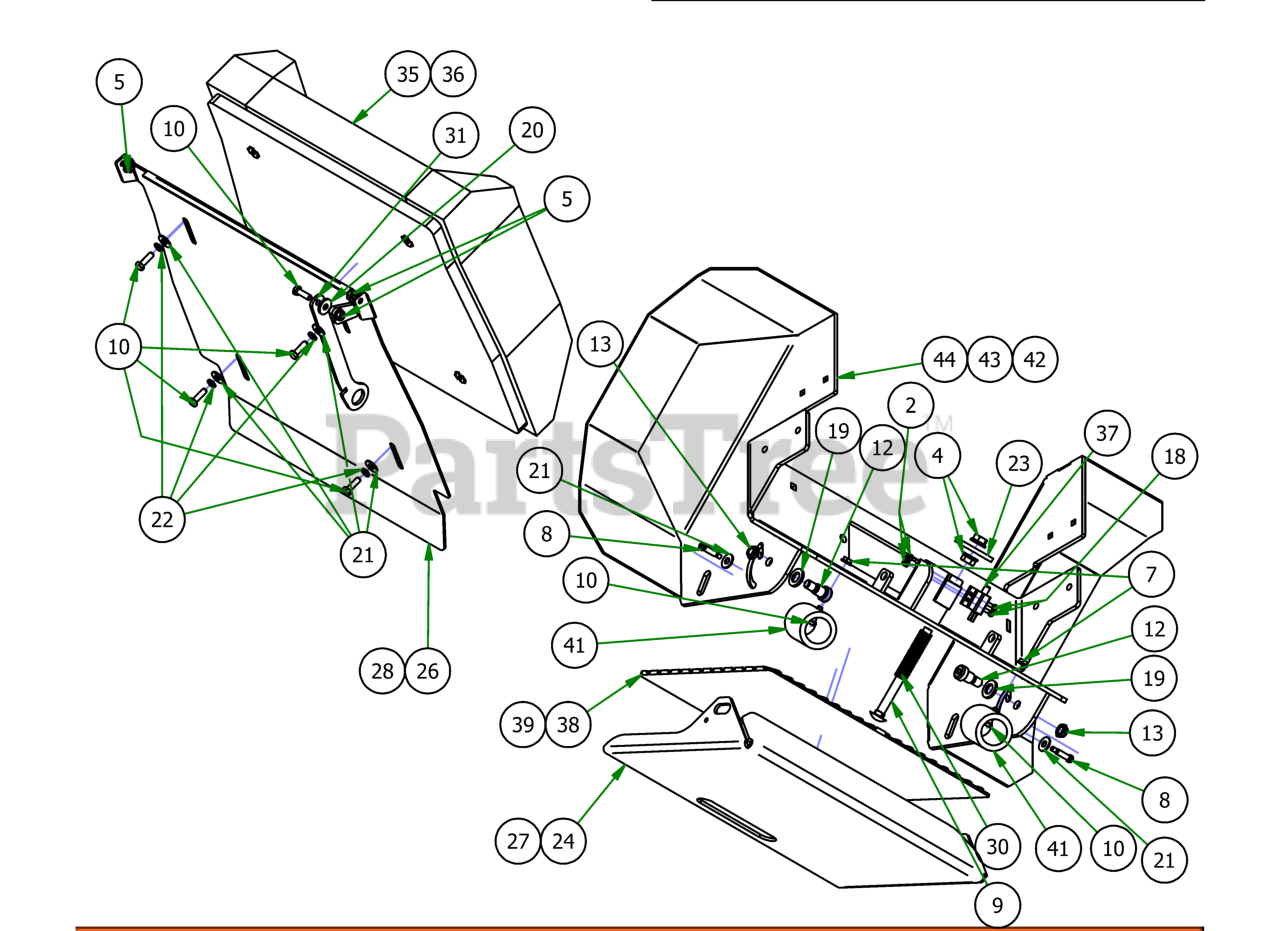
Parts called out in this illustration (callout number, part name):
1	3326 Wellnut (1/4-20 x 5/18")
2	10-24 Nylon Insert Locknut Zin
3	3/8 Nylock Flange Nut
4	1/2-13 HEX SERRATED FLANGE NUT HARD/ZINC
5	5/16-18 Nylon Flange Nut
6	1/4-20 Nylon Insert Locknut Zi
7	5/16-18 Hex Flange Nuts Zinc w
8	Steel Shoulder Screw 1/4"-20 x 7/8" Diameter 5/16"
9	1⁄2-13 x 6 Carriage Bolt, 2” min threads, Grade 2
10	5/16-18 X 1 GR 5 Hex Bolt Zinc
11	3/8-16 X 2 HEX CAP SCREW (GR.5) ZINC
12	5/8 X 5/8 SOCKET SHOULDER BOLT ZINC YELLOW
13	1/2-13 NYLON INSERT JAM LOCKNUT ZINC
14	5/16-18 X 1-1/4 CARRIAGE BOLT ZINC
15	3/8-16 X 1-1/4 HEX CAP SCREW (GR.5) ZINC
16	3/8-16 X 1-1/4 Carriage Bolt
17	1/4-20 X 3/4 GR 5 Hex Bolts
18	10-24 X 3/4 BUTTON SOCKET CAP SCREW 18-8 STAINLESS STEEL
19	.635 ID X 1.120 OD X .140 THICK FLAT WASHER NYLON
20	.360 ID X .983 OD X .120 THICK FLAT WASHER NYLON
21	5/16 USS FLAT WASHER (7/8 OD) ZINC
22	5/16 SPLIT LOCKWASHER ZINC
23	MZ Deck Idler Spacer
24	2019 Stand-On Platform
25	2019 Stand On Access Panel
26	2019 Stand On Pad Plate Weldment
27	2020 36" Stand-On Platform Plate-RAW
28	2020 36 Stand On Pad Plate Weldment
29	1/4"-20 x 3/4" Knurled Thumb Screw
30	Rider Presence Spring 9657K145
31	2019 Stand On Operator Pad Kickstand
32	Outlaw Throttle Cable
33	2019 Stand On Frame Weldment
34	2020 36 Stand On Frame Weldment
35	2019 Stand-On Platform Pad
36	2020 36" Stand-On Platform Pad
37	safety Switch
38	2019 Stand On Mat
39	2020 36 Stand On Mat
40	2019 Revolt Wiring Harness
41	GBR-647 Miner Elastomer
42	Stand On Platform Support_61 weldment
43	2020 36" Stand On Platform Support weldment
44	2019 Stand On Platform Support weldment
